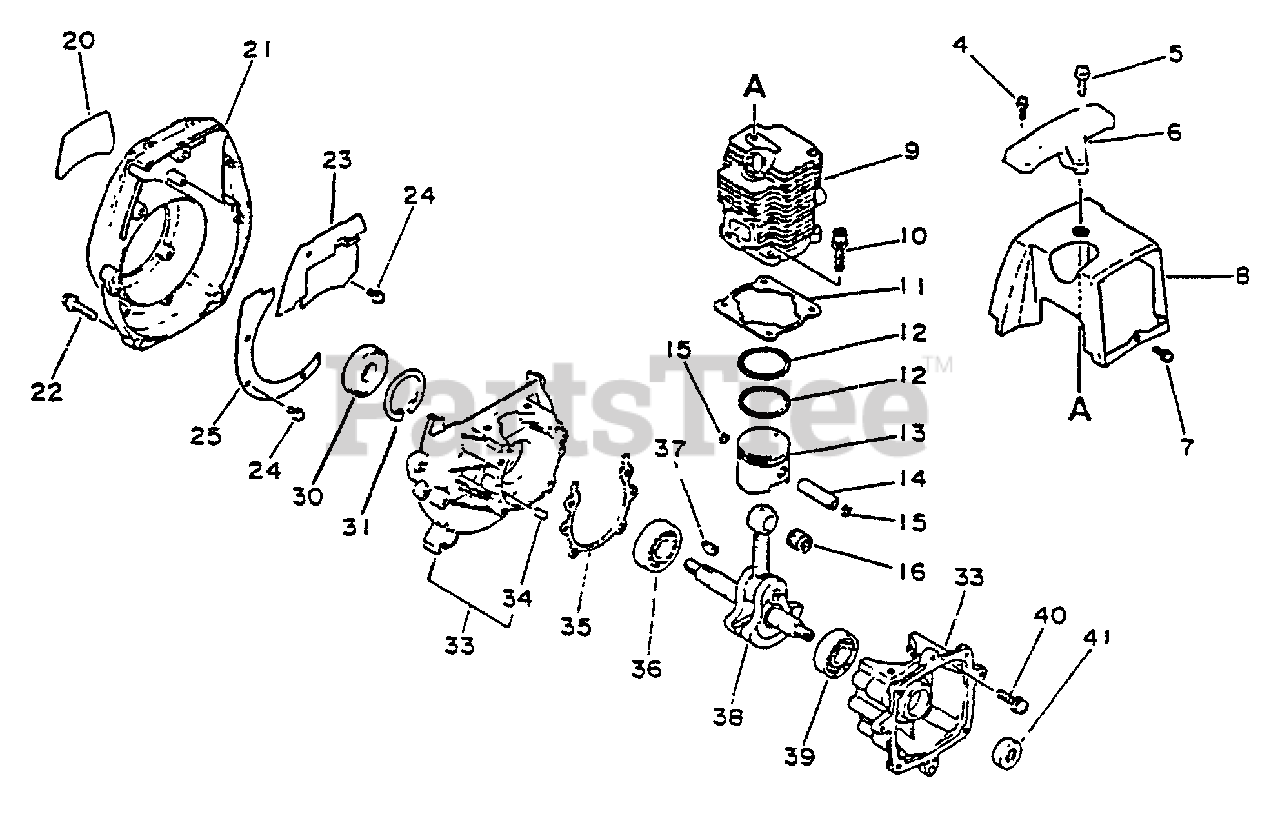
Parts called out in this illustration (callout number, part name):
4	SCREW 4×14
5	SCREW 5×16
6	GUARD, TOP
7	SCREW 4×10
8	COVER, ENGINE - ORANGE
9	CYLINDER
10	BOLT 5×20
11	GASKET, CYLINDER
12	RING, PISTON
13	PISTON
14	PIN, PISTON
15	RING, SNAP
16	BEARING, NEEDLE
20	LABEL - MODEL
21	COVER, ENGINE - ORANGE
22	SCREW 5×20
23	PLATE, GUIDE
25	PLATE, GUIDE
30	SEAL, OIL 12
31	RING, RETAINING - 32
33	CRANKCASE KIT
34	PIN, LOCATING 4
35	GASKET, CRANKCASE
36	BEARING, BALL - 6201 C3
38	CRANKSHAFT ASSY
39	BEARING, BALL 6001
40	SCREW 5×25
41	SEAL, OIL 12
